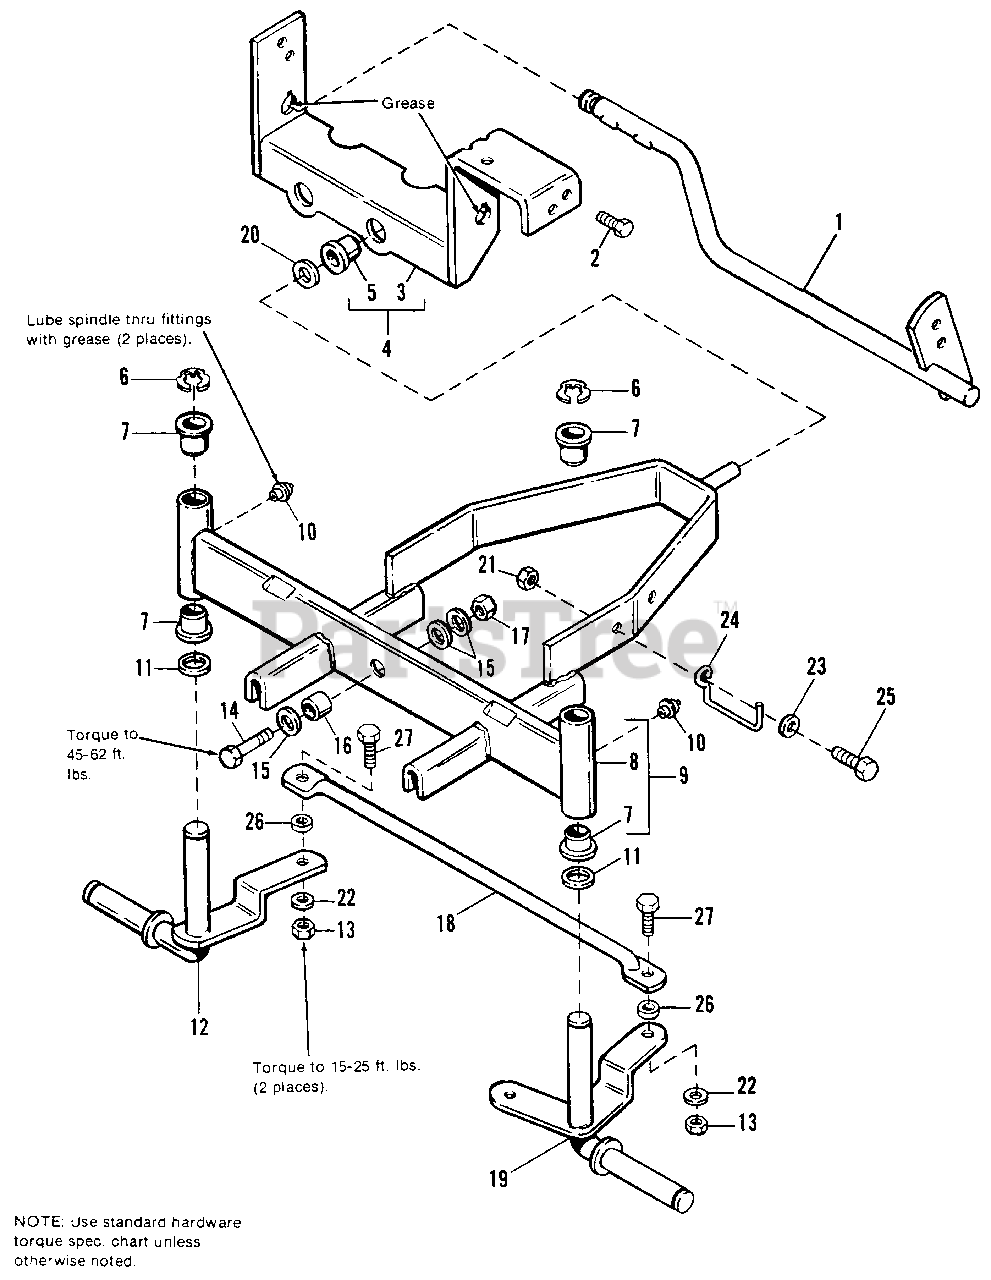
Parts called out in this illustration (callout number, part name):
1	LEVER ASSY., Brake
2	SCREW, Taptite, 5/16-18 x 3/4
4	SUPPORT ASSY., Rear w/Bushing (Includes Ref. No. 3 & 5)
6	"E" RING, Ext. 3/4
9	AXLE ASSY., Front (Includes Ref. No. 7 & 8)
10	FlTTING, Lube, Drive Type
11	WASHER
12	SPINDLE ASSY. R.H.
13	LOCKNUT, Hex, 3/8-16
14	CAPSCREW, Hex, 1/2-13 x 1-3/4, Gr. 8
15	WASHER, 9/16
16	SPACER
17	LOCKNUT, Hex, 1/2-13
18	TIE ROD ASSY.
19	SPINDLE ASSY., L.H.
20	WASHER, 5/8
21	NUT, Hex, 5/16-18
22	WASHER, 3/8
23	WASHER, 5/16
24	GUIDE, Drag Link
25	CAPSCREW, Hex Hd., 5/16-18 x 1
26	SPACER, Spindle
27	CAPSCREW, 3/8-16 x 1
